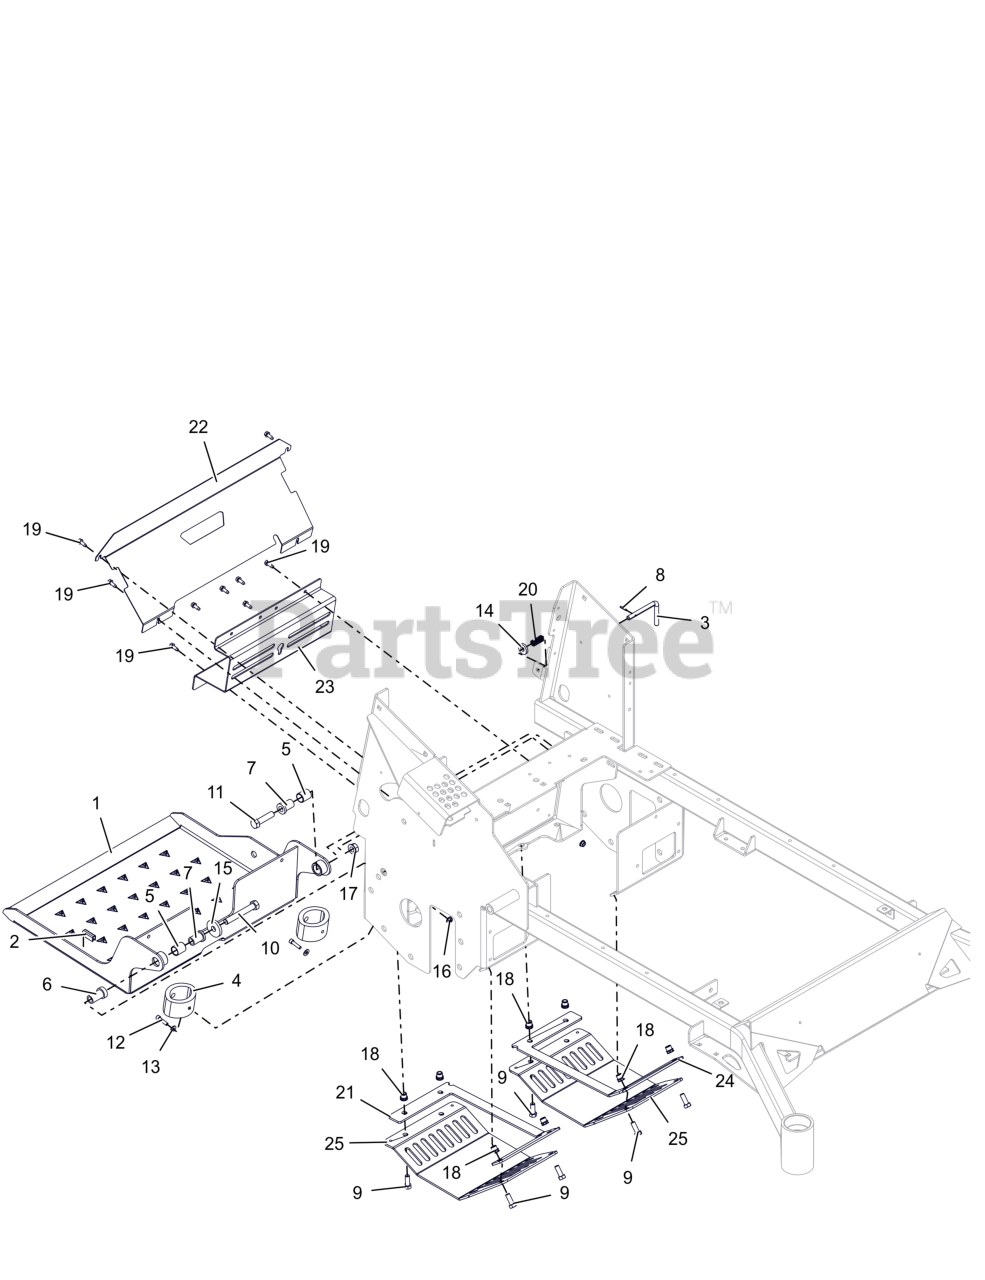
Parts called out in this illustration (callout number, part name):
1	WLDMT, OPERATOR PLATFORM (BLACK)
2	STRIP, COWL
3	PIN- PLATFORM LOCK
4	BUMPER, PLATFORM
5	BRG, .750 X .875 X 1.000
6	BSHG-FLG .515X.746X1.681X1.000
7	BSHG-FLG .515X.746X1.290X1.000
8	PIN-ROLL .125X.75
9	BLT, HEX .38-16X1.00 G8ZCCEP30
10	BLT, HEX .50-13X3.50F G5 ZCC
11	BLT, HEX .50-13X2.00 G5 ZCC
12	SCR, SKH .25-20X1.00
13	WSHR,FLT .281X.625X.065 ZCC
14	WSHR, FLT .406X1.00X.188 ZCC
15	WSHR-FL-STL .515X1.625X.250 YZ
16	NUT-LK-CTR-FLG .25-20 ZC120
17	NUT-LK-CTR-FLG .500-13 GG ZCC
18	NUT, THREADED INSERT .38-16 ZC120
19	SCR,TAP .25-20X.625 HWH ZCC
20	SPRING, COMPRESSION
21	PLATE, SKID TENSION (BLACK)
22	PANEL- GUARD
23	GUARD, FOOT (ORANGE)
24	PLATE- LH SKID TENSION
25	PLATE, SKID (BLACK)
